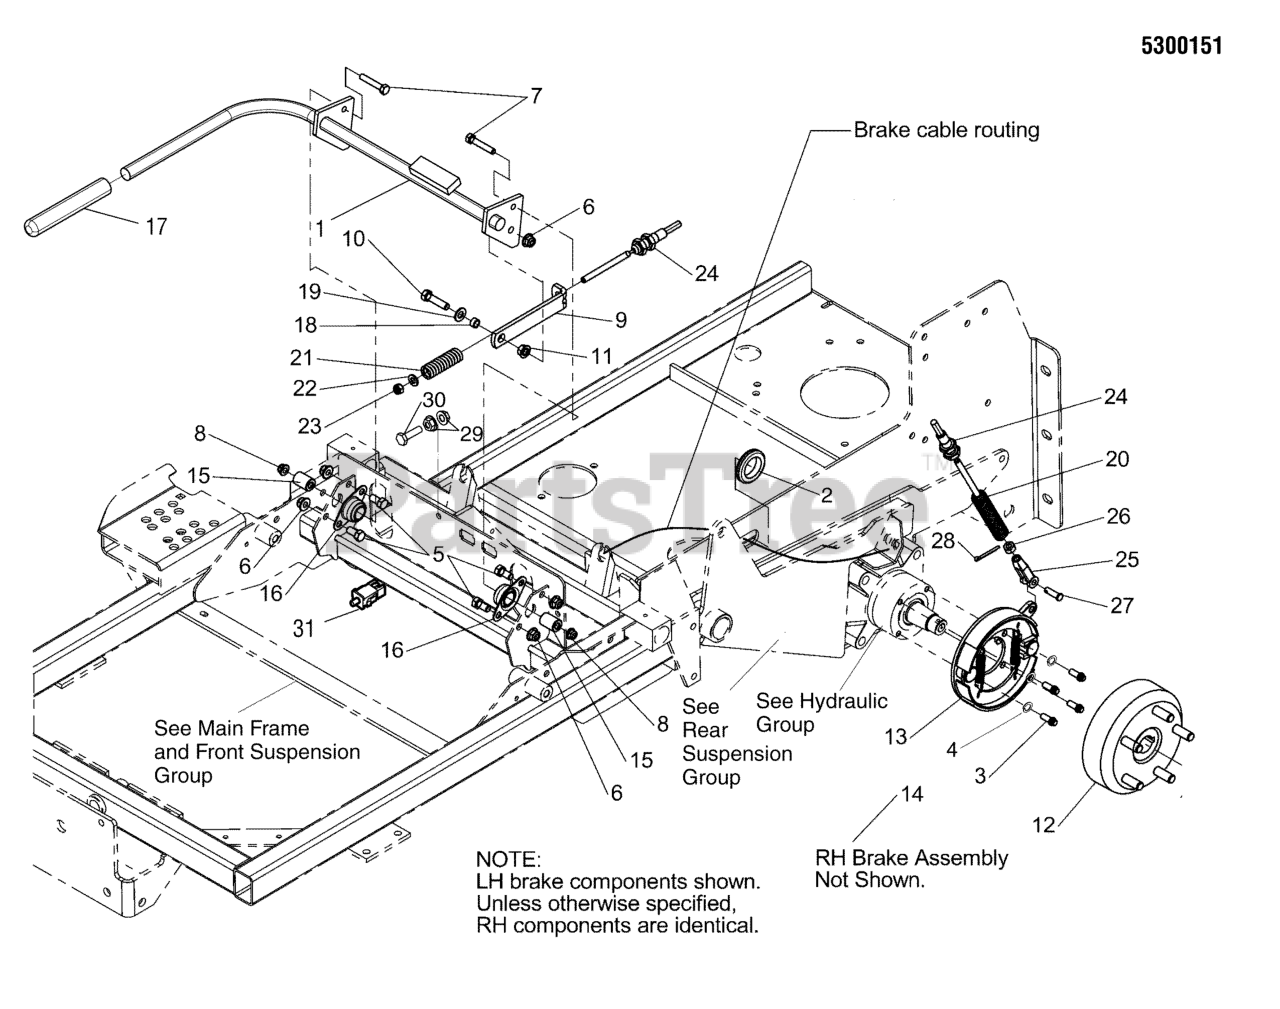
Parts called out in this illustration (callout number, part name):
1	WELD, BRAKE SHAFT - BLK
2	GROMMET, 1-1/4"
3	BOLT, 5/16-18 X 3/4 12PT FLANGE - PATCH
4	WASHER, 5/16 LOCK CZ
5	BOLT, 3/8-16 X 3/4" GD5 CZ
6	NUT, 3/8-16 HEX NYLOCK FLANGE
7	BOLT, 5/16-18 X 1-3/4" GD5 YZ
8	NUT, 5/16-18 Hex Nylock Flange
9	LINK, BRAKE LOCK - BLK
10	BOLT, 3/8-16 X 1-1/2" GD5 CZ
11	NUT, 3/8-16 HEX SERRATED FLANGE
15	SPACER, .32 X .75 X 1.06
16	BEARING, BRONZE FLANGE, 3/4
17	GRIP, FOAM, 3/4 ID X 6 X .187
18	SPACER, .38 X .50 X .27
19	WASHER, 3/8 SAE
20	SPRING, COMPRESSION
21	SPRING, COMPRESSION
22	WASHER, 5/16" SAE
23	NUT, 5/16-24 HEX NYLON LOCK
24	CABLE, PARKING BRAKE IS2000
25	CLEVIS, 5/16-24, STEEL, CLEAR ZINC
26	NUT, 5/16-24 HEX
27	CLEVIS PIN, 5/16" X 1"
28	PIN, HAIR, .0585 X 1-1/8, 1/4 EYE, YZ
29	NUT, 5/16-18 HEX SERRATED FLANGE (LARGE)
30	BOLT, 5/16-18 X 1-1/4"GD5 YZ
31	SWITCH, DP NO/NC SNAP-IN
